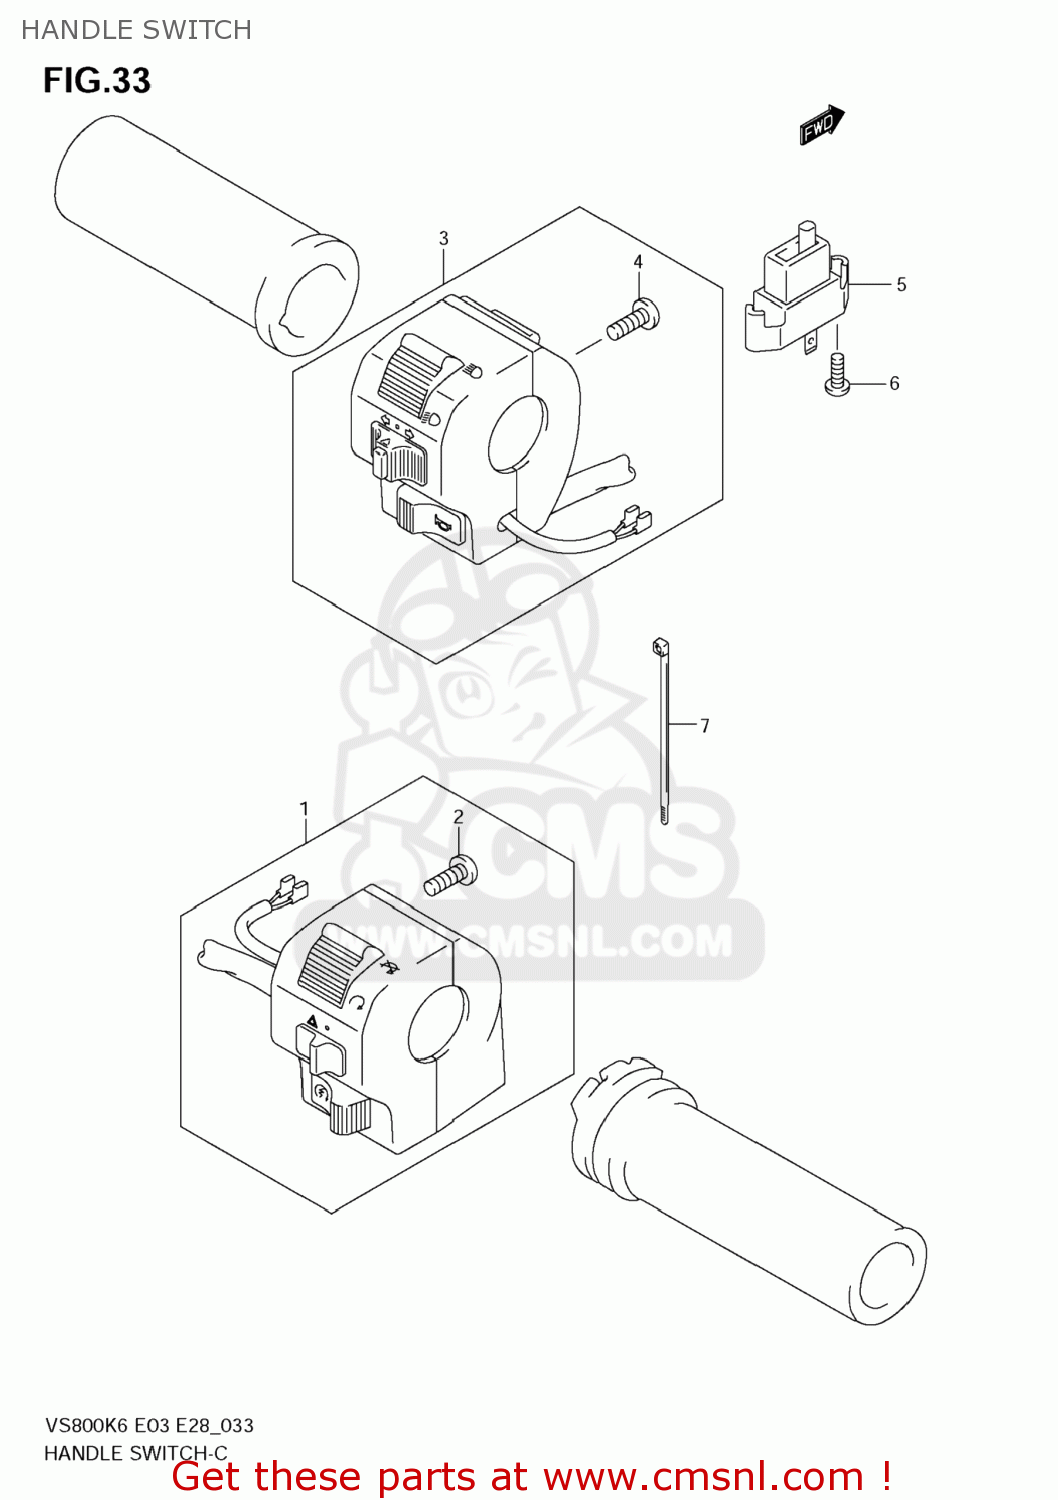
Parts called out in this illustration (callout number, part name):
1	SWITCH ASSY,HANDLE,R
2	SCREW
3	SWITCH ASSY,HANDLE,L
4	SCREW
5	SWITCH ASSY,CLUTCH
6	SCREW
7	CLAMP(L:145)
